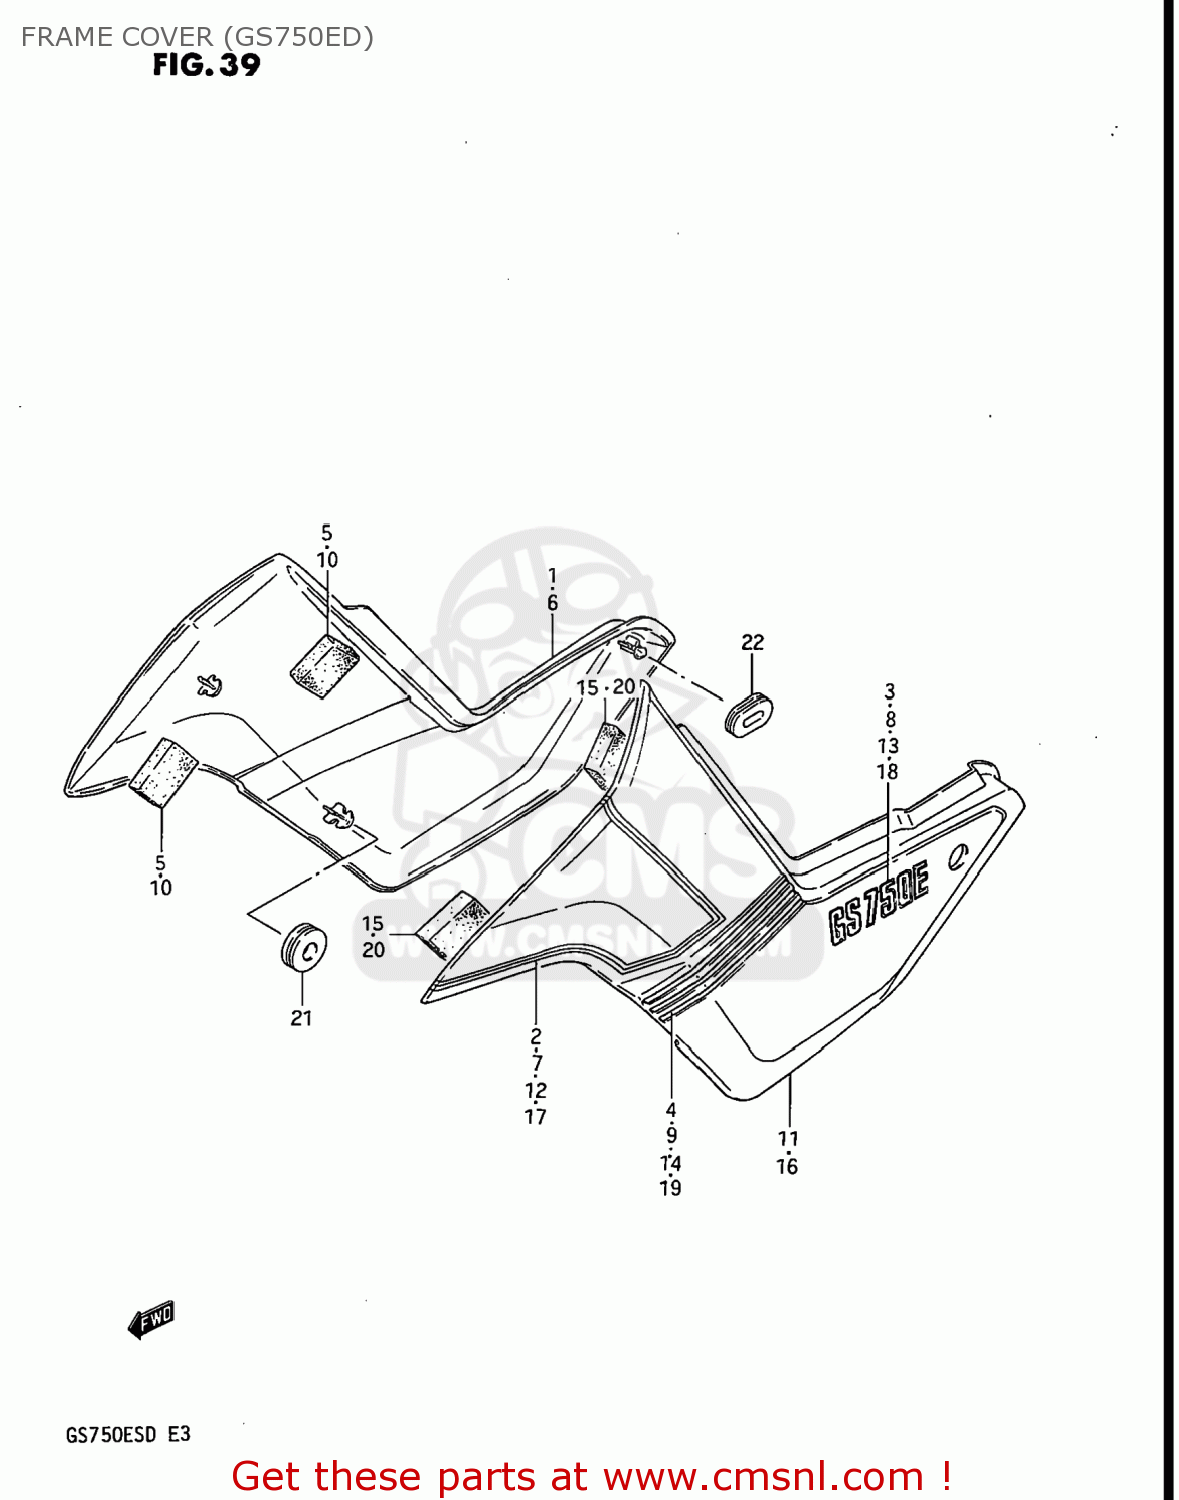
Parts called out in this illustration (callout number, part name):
1	COVER,FRAME,RIGHT
2	TAPE SET,FRAME COVER
3	EMBLEM
4	DENT,FRAME COVER,RIGHT
5	CUSHION
6	COVER,FRAME,RIGHT
7	TAPE SET,FRAME COVER
8	EMBLEM
9	DENT,FRAME COVER,RIGHT
10	CUSHION
11	COVER,FRAME,LEFT
12	TAPE SET,FRAME COVER
13	EMBLEM
14	DENT,FRAME COVER,LEFT
15	CUSHION
16	COVER,FRAME,LEFT
17	TAPE SET,FRAME COVER
18	EMBLEM
19	DENT,FRAME COVER,LEFT
20	CUSHION
21	CUSHION
22	CUSHION
